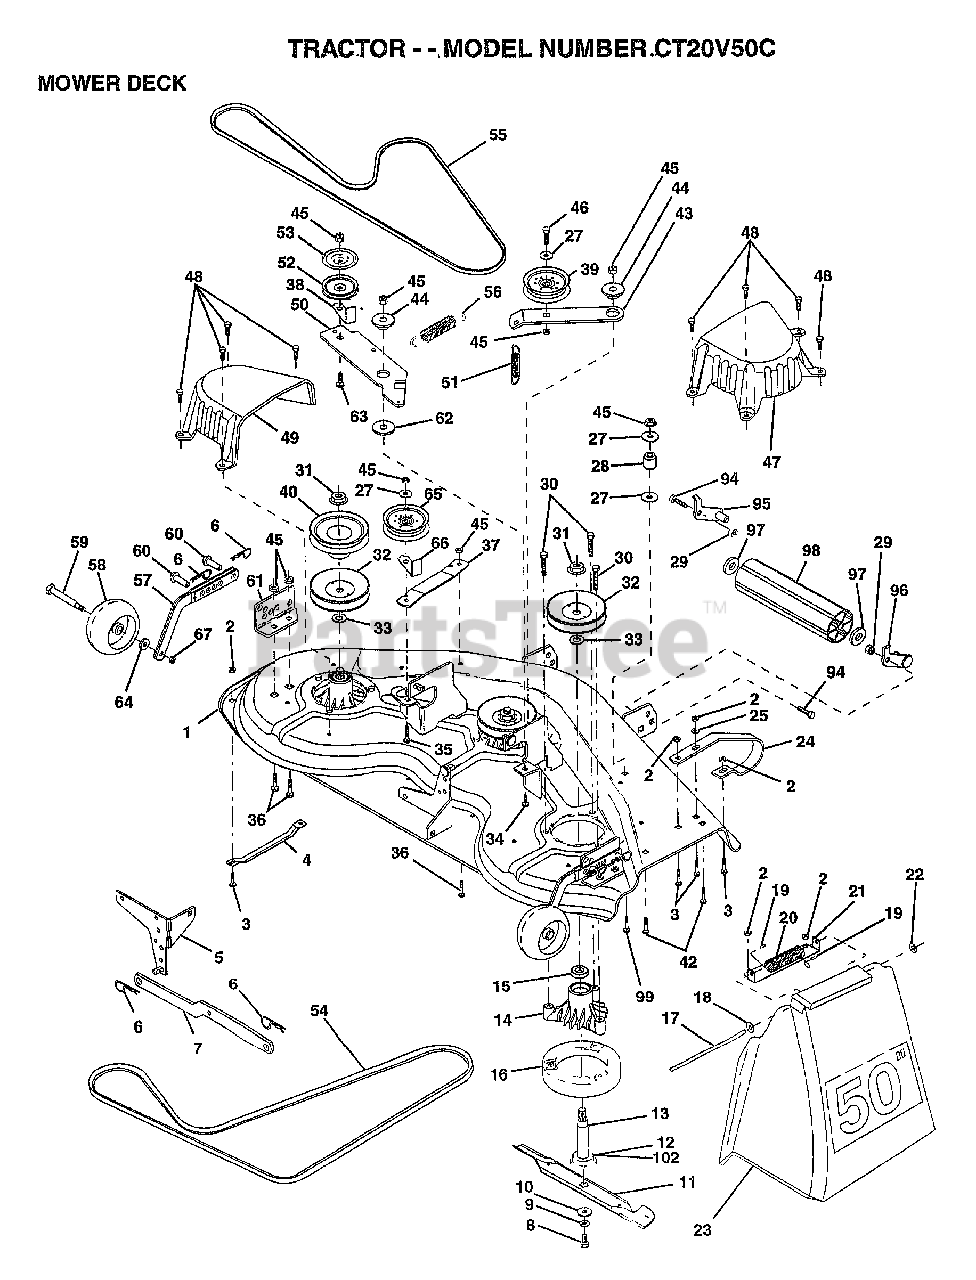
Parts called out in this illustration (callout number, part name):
1	"DECK ASM-50"""
4	RUNNER-LH M
5	BRKT.ASM.SW.44/50
8	BLADE BOLT
10	WASHER.HARD.BLADE
11	"BLADE.50"" HD"
12	BEARING.BALL
13	SHAFT.ASM.W/BRNG
14	HOUSING.MAND.44.V
15	BEARING
16	STRIPPER RND MWR
17	ROD-HINGE T
18	WASHER
19	CAP-SLEEVE LT
20	SPRING TORSION
21	BRKT DEFLECTOR
22	NUT PUSH M
23	DEFLECTOR
24	"RUNNER RH 50"" DK"
25	WASHER M
27	WASHER
29	NUT
32	PULLEY.MANDREL.42
33	WASHER
34	BOLT.3/8-14X1.25
35	BOLT
36	BOLT D
37	STIFFENER.ARM.IDL
38	"KEEPER-BELT,IDLER"
39	FLAT IDLER PULLEY
40	"PULLEY.DRIVEN.44"""
42	BOLT
43	"ARM.IDLER.SEC.44"""
44	SPACER RETAINER
47	"COVER.MAND.RH.44"""
48	SCREW.1/4-20X5/8
49	COVER.MANDREL.LH
50	ARM.IDLER.PRIMARY
51	"SPRING.SEC.44""VEN"
52	PULLEY.IDLER.VGRO
53	SHIELD.IDLER.44.V
54	BELT V PRIM 50
55	BELT-V.SEC.46.KEL
56	SPRING.EXT.DECK.
57	BAR.ASM.GUAGE.WHL
58	WHEEL.GUAGE.MED.
59	BOLT.SHOULDER
60	PIN.CLEVIS
61	BRACKET.GUAGE.WHL
62	HARDENED WASHER
63	BOLT.3/8-16X1.50
64	WASHER
65	PULLEY IDELR FLAT
66	"KEEPER-BELT,IDLER"
67	LOCKNUT
94	BOLT
97	WASHER
99	BOLT
102	WASHER.FELT.
